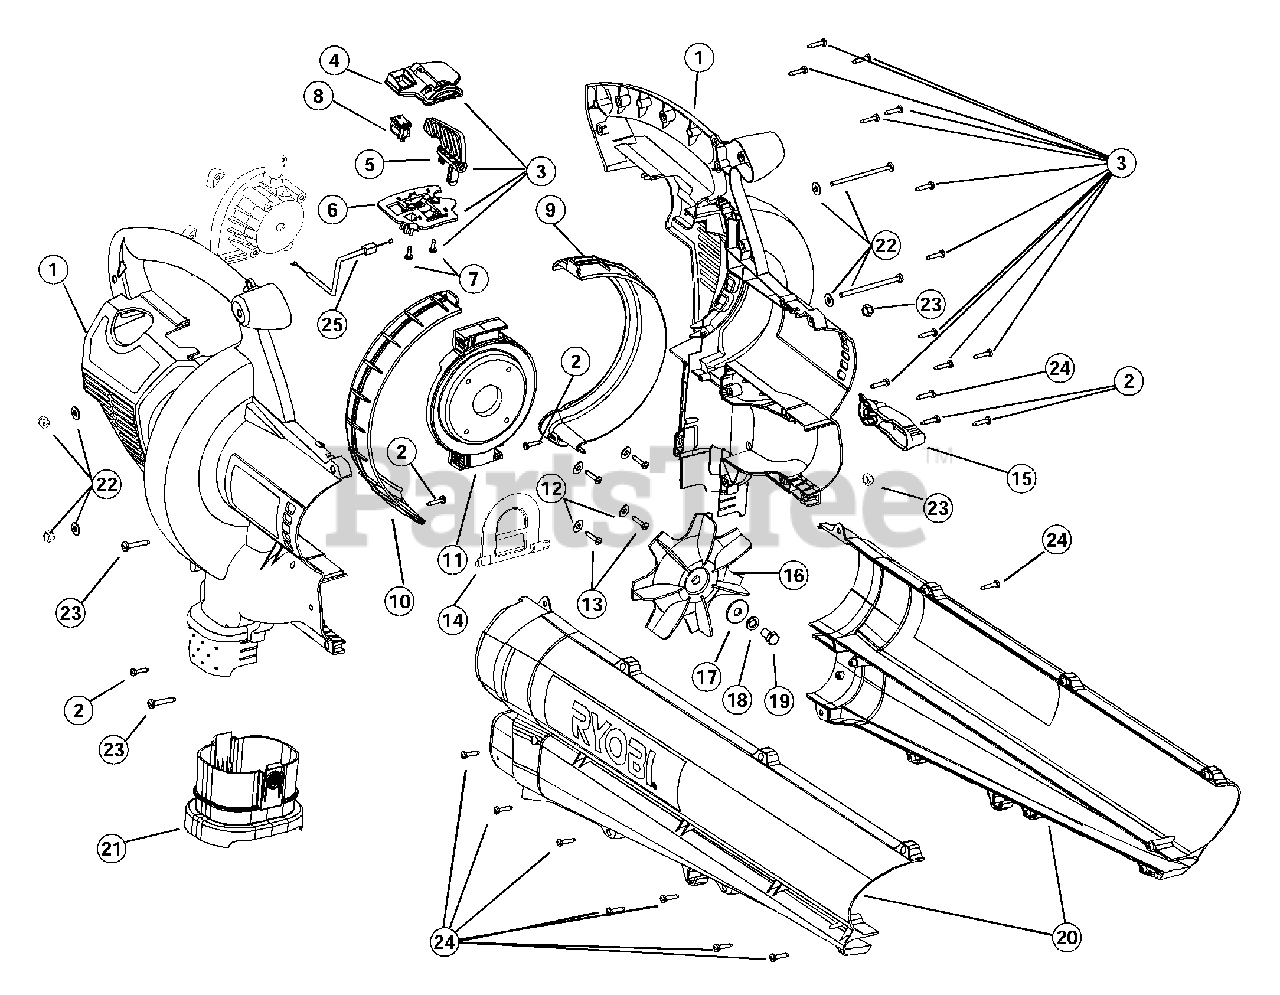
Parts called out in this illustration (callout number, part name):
1	Engine Cover Assembly
2	Cover Screw
3	Throttle Control Assembly
4	Upper Throttle Control Plate
5	Throttle Control Lever
6	Lower Throttle Control Plate
7	Screw, Plastic
8	Rocker Switch Assembly
9	Left Side Liner
10	Right Side Liner
11	Engine Mounting Plate
14	Mode Control Flapper
15	Mode Control Lever
16	Impeller Blade
17	Washer
18	Lock Washer
20	Blower/Vac Tube Assembly
21	Vacumm Bag Adapter
22	Mounting Plate Hardware
23	Blower/Vac Tube Mounting Hardware
25	Throttle Cable
